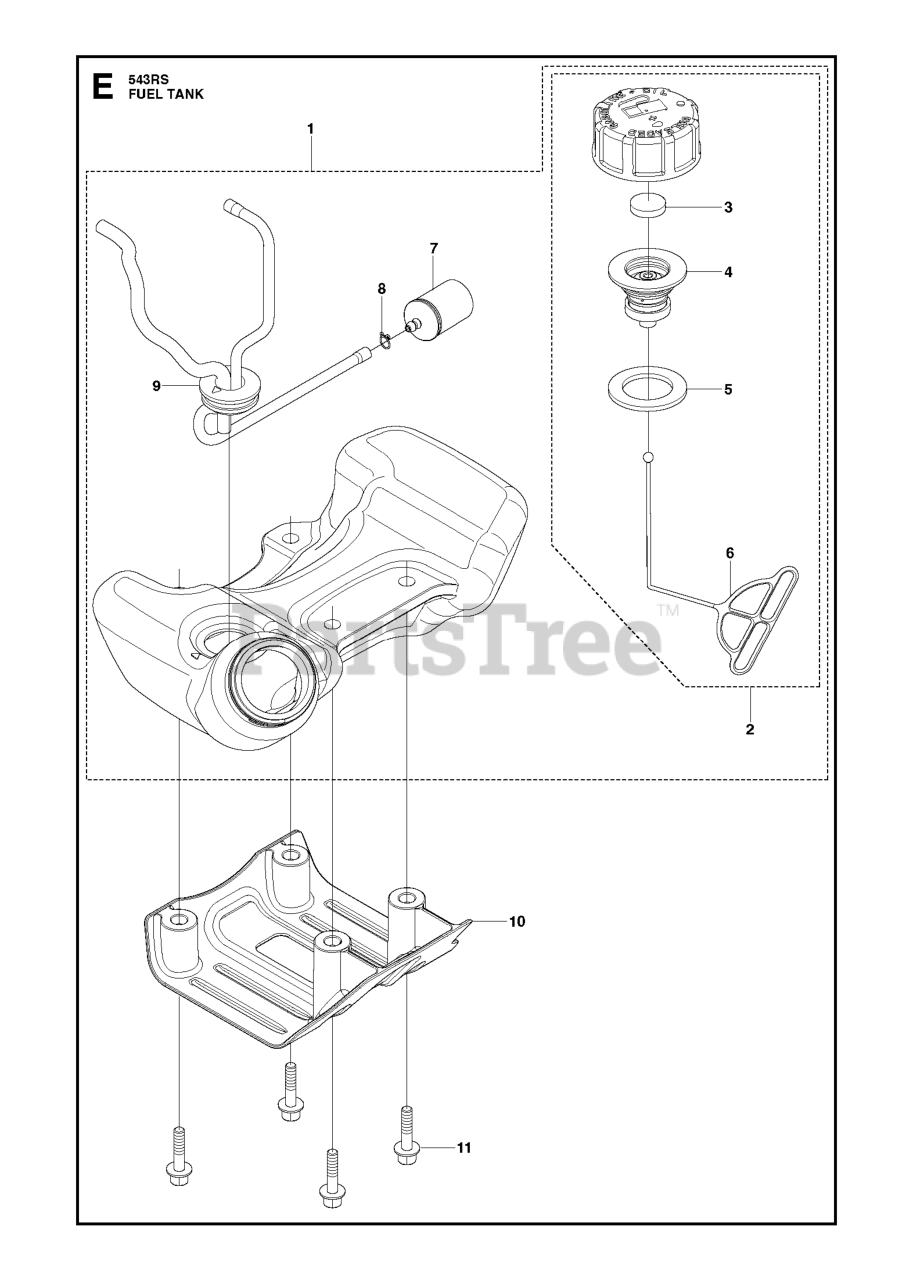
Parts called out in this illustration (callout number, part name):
2	ASSY FUEL CAP
7	RP FUEL FILTER
10	GUARD, TANK
11	BOLT M5X25
